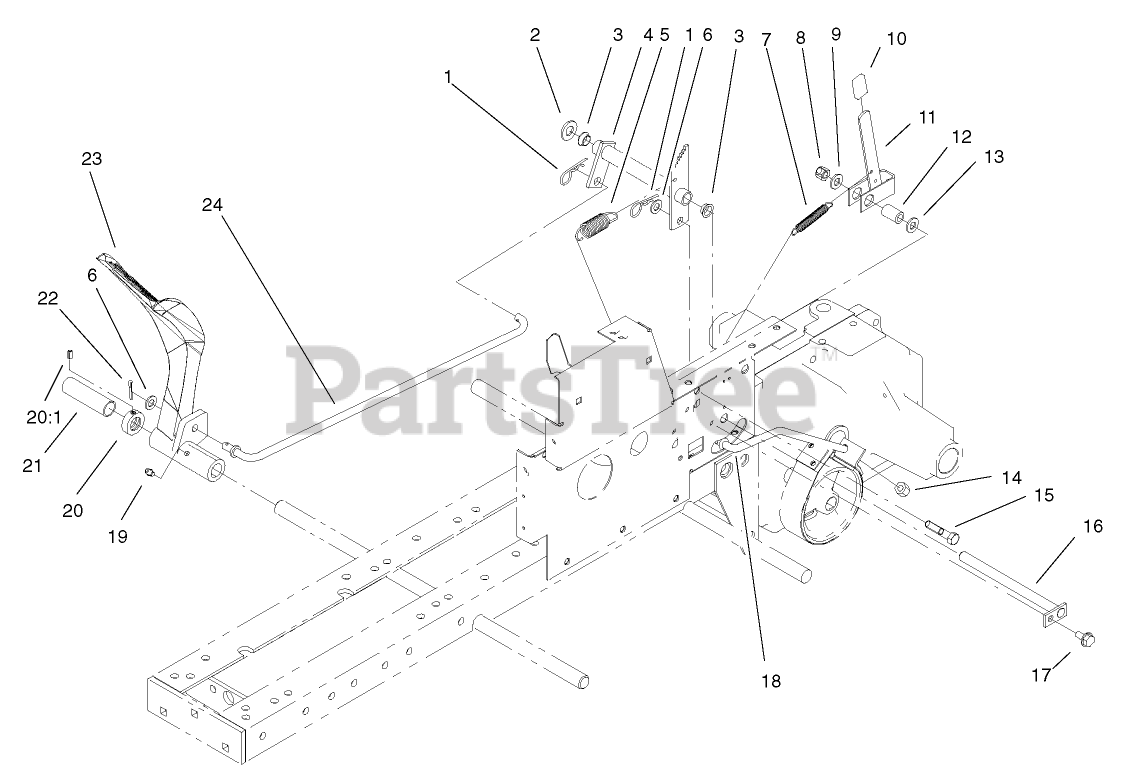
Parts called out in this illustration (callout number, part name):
1	PIN-HAIR
2	WASHER-FLAT
3	BUSHING-FLANGED
4	BELCRANK ASM
5	SPRING-EXTENSION
6	WASHER-NYLON
7	SPRING-BRAKE
8	NUT-LOCK, NI
9	WASHER-FLAT
10	GRIP
11	BRAKE LEVER ASM
12	SPACER
13	WASHER-FLAT
14	NUT-LOCK, NI
15	SCREW-HH
16	ROD ASM
17	SCREW-HWHTF
18	ROD-REAR BRAKE
19	FITTING-GREASE
20	COLLAR
20:1	SCREW-HSH
21	SLEEVE-PROTECTIVE
22	PIN-COTTER
23	PEDAL-BRAKE, GEAR
24	ROD-BRAKE
